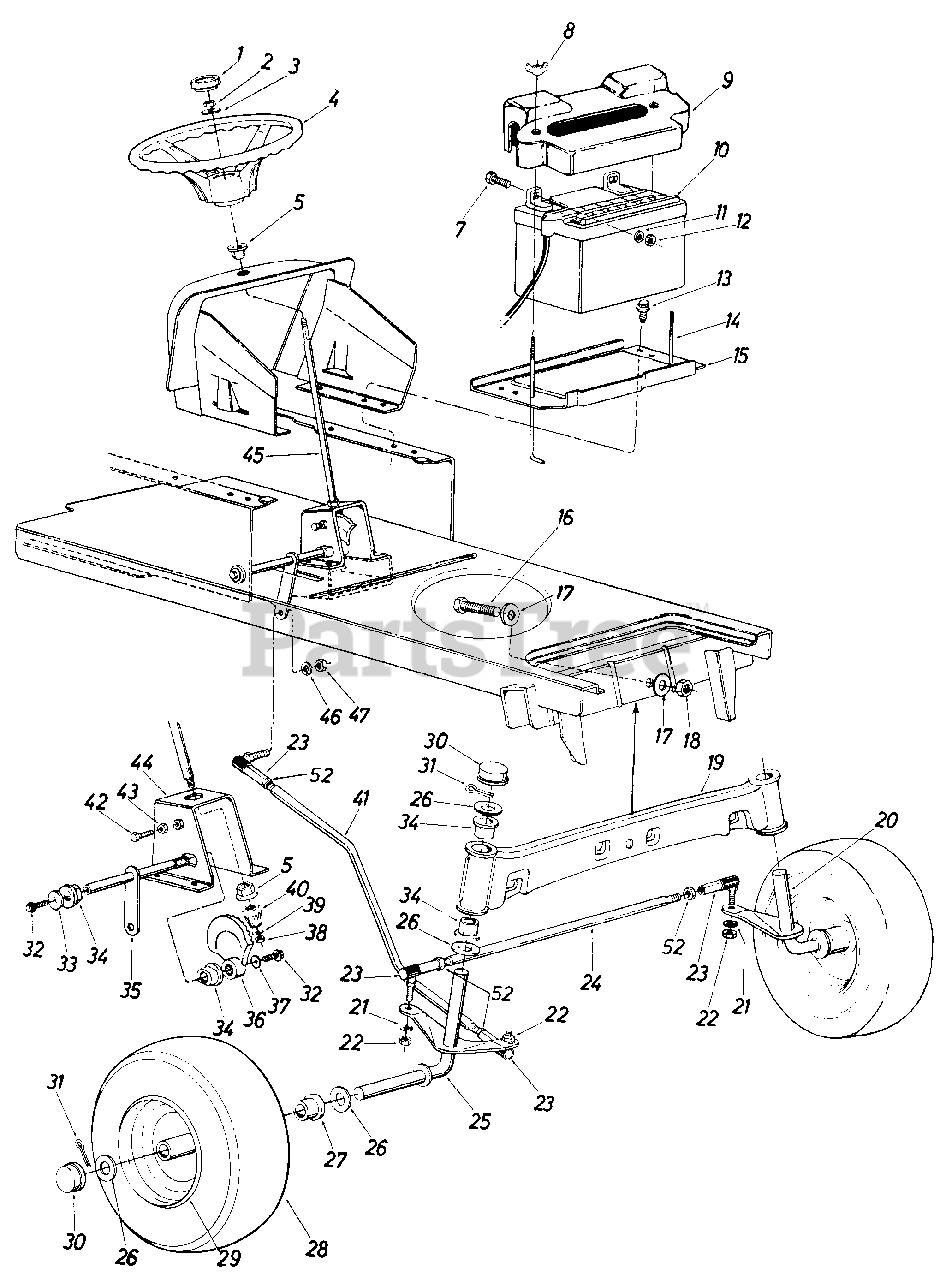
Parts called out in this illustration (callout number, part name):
1	Steering Wheel Cap
2	Hex L-Nut 5/16-18 Thd.
3	Bell-Wash. 5/16" I.D. x .87" O.D. x .060
4	Steering Wheel
5	Plastic Hex Bearing 5/8" I.D.
7	Hex Scr 1/4-20 x .62" Lg.
8	Wing Nut Plastic 1/4-20 Thd.
9	Battery Cover
10	12-V Battery
11	L-Wash. 1/4" Scr.*
12	Hex Nut 1/4-20 Thd.
13	Hex Thd. Rolling Scr. 1/4-20 x .50" Lg.
14	Battery Hold Down Rod
15	Battery Plate
16	Hex Scr. 5/8-18 x 2.50" Lg.
17	Flat Wash. .66" I.D. x 2.25" O.D. x .17
18	Hex Cent. L-Nut 5/8-18 Thd.
19	Front Pivot Bar Ass'y.
20	Front Axle Ass'y. L.H.
21	L-Wash. 3/8" Scr.
22	Hex Nut 3/8-24 Thd.
23	Ball Joint Ass'y.
25	Front Axle Ass'y. R.H.
26	Fl-Wash. .780 I.D. x 1.59 O.D.
27	Flange Bearing
28	Front Wheel Ass'y. Comp.
29	Front Wheel Rim Only
30	Dust Cover
31	Cotter Pin 5/32" Dia. x 1.00" Lg.
32	Hex Scr. 3/8-24 x .75" Lg. Grade 5
33	Fl-Wash. 3/8 I.D. x 1.25 O.D. x .090
34	Flange Double "D" Brg. .753 I.D.
35	Steering Arm Shaft Ass'y.
36	Side Gear Steering
37	Bell-Wash. 3/8" I.D.
38	Hex Cent. L-Nut 5/16-24 Thd.
39	Fl-Wash. 5/16" I.D. x .62 O.D. x .059
40	Pinion Gear Steering
42	Hex Nylon Scr. 3/8-16 x 1.25" Lg.
43	Hex Nut 3/8-16 Thd.
44	Steering Gear Sup. Ass'y.
45	Steering Shaft
46	L-Wash. 3/8" Scr.
47	Hex Nut 3/8-24 Thd.
52	Hex Jam Nut 3/8-24 Thd.
